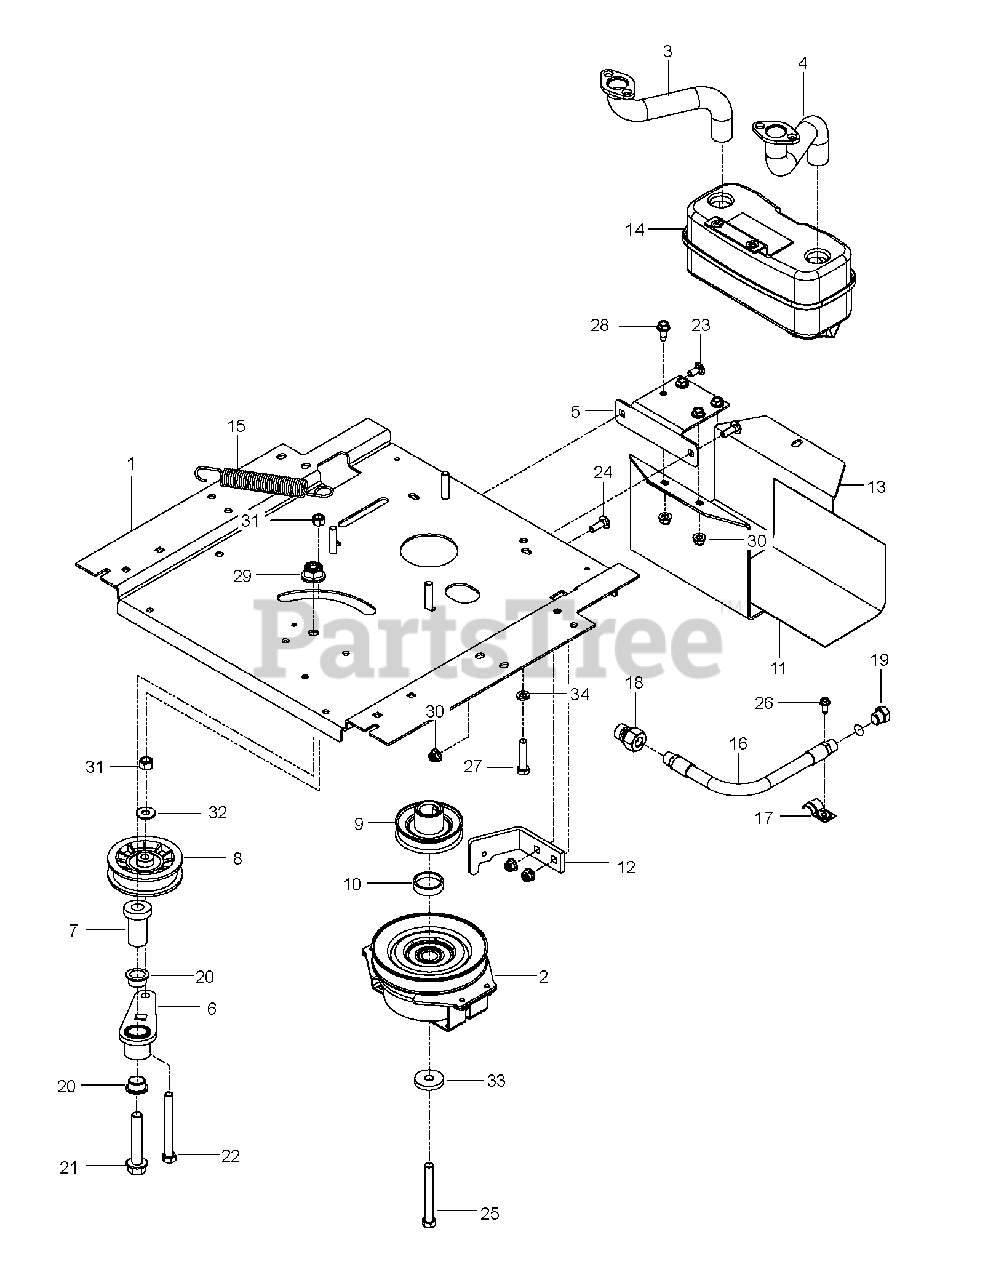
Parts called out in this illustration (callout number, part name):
1	PLATE.ENGINE.PNT.23"FRAME.EDIP
2	CLUTCH.OGURA.5.0PD.GT1.5A-EH07
3	TUBE.EXHAUST.RH.FR961/FR730
4	TUBE.EXHAUST.LH.FR961/FR730
5	BRACKET MUFFLER MS431BLK
6	ARM IDLER
7	SPINDLE.IDLER
8	PULLEY, IDLER RAKE & ZTR
9	PULLEY.ENGINE
10	SPACER.SPACER.625 W/OGURA.LCC
11	HEAT SHIELD
12	CLUTCH.STOP.OGURA LCC.BLACK
13	GUARD.MUFFLER.WO.TOW.HITCHX431
14	MUFFLER ASM TWIN
15	SPRING, DECK DRIVE
16	HOSE.ASSEMBLY.OIL.DRAIN
18	ADAPTER, OIL DRAIN
19	PLUG OIL DRAIN
20	BEARING.FLANGED.PLASTIC.3/4ID
21	BOLT.FLANGE.1/2-13 X 2.75.GRD5
22	HCS 3/8-16X3-1/2 TAPBLT GR5 ZD
23	BOLT 5/16-18 X3/4 ZN/YEL GR 5
25	CLUTCH BOLT7/16-20X3.5 GR524HR
26	SCR 1/4-20X5/8 HEX SELF TAP ZD
27	BOLT, HCS 3/8-16X1-3/4
28	SCREW
29	NUT, 1/2-13 HEX FLG NYLOC ZD
30	5/16-18 NYLOC FLANGE NUT
31	NUT 3/8-16 NYLOC
32	WASHER
34	LOCKWASHER
